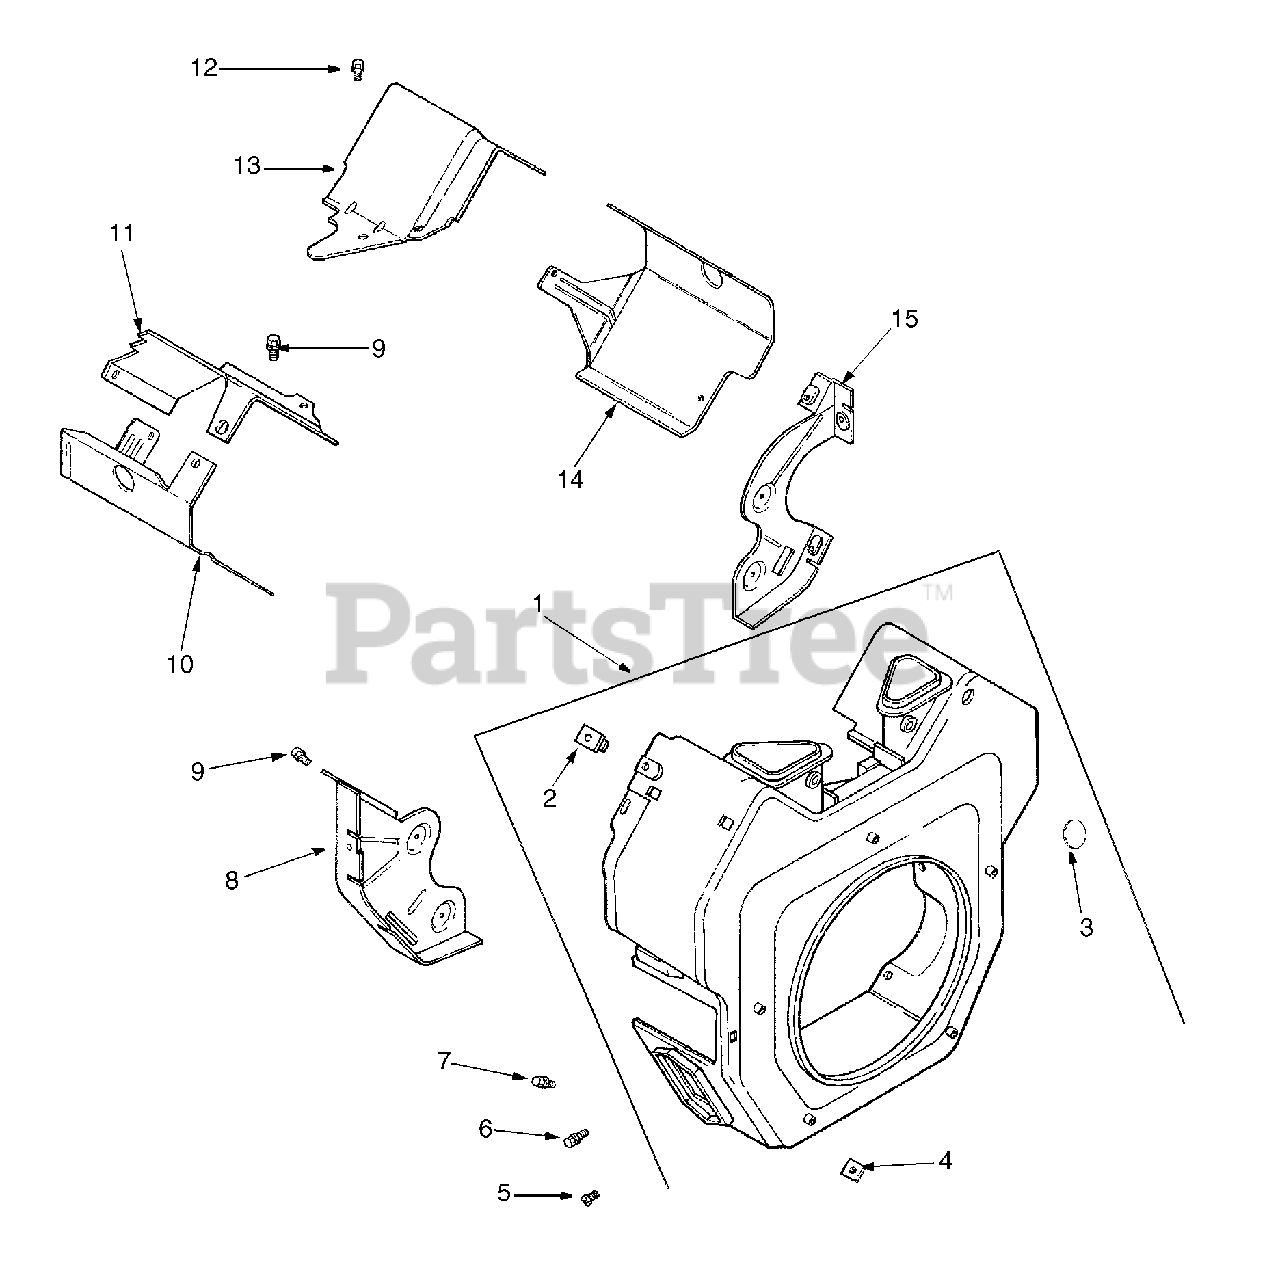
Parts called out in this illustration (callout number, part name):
1	Housing, Blower
2	Nut, Plastic
3	Plug, Button 9/16"
4	Nut, Plastic
5	Screw, Hex Flange M5 x 0.8 x 16
6	Screw, Hex Flange M5 x 0.8 x 16
7	Screw, Hex Flange M5 x 0.8 x 20
8	Plate, Backing #2 Side
9	Screw, Hex Flange M6 x 1.0 x 16
10	Baffle, Cyl Barrel #2 Side
11	Baffle, Valley #2 Side
12	Screw, Hex Flange M5 x 0.8 x 10
13	Baffle, Valley #1 Side
14	Baffle, Cyl Barrel #1 Side
15	Plate, Backing #1 Side
